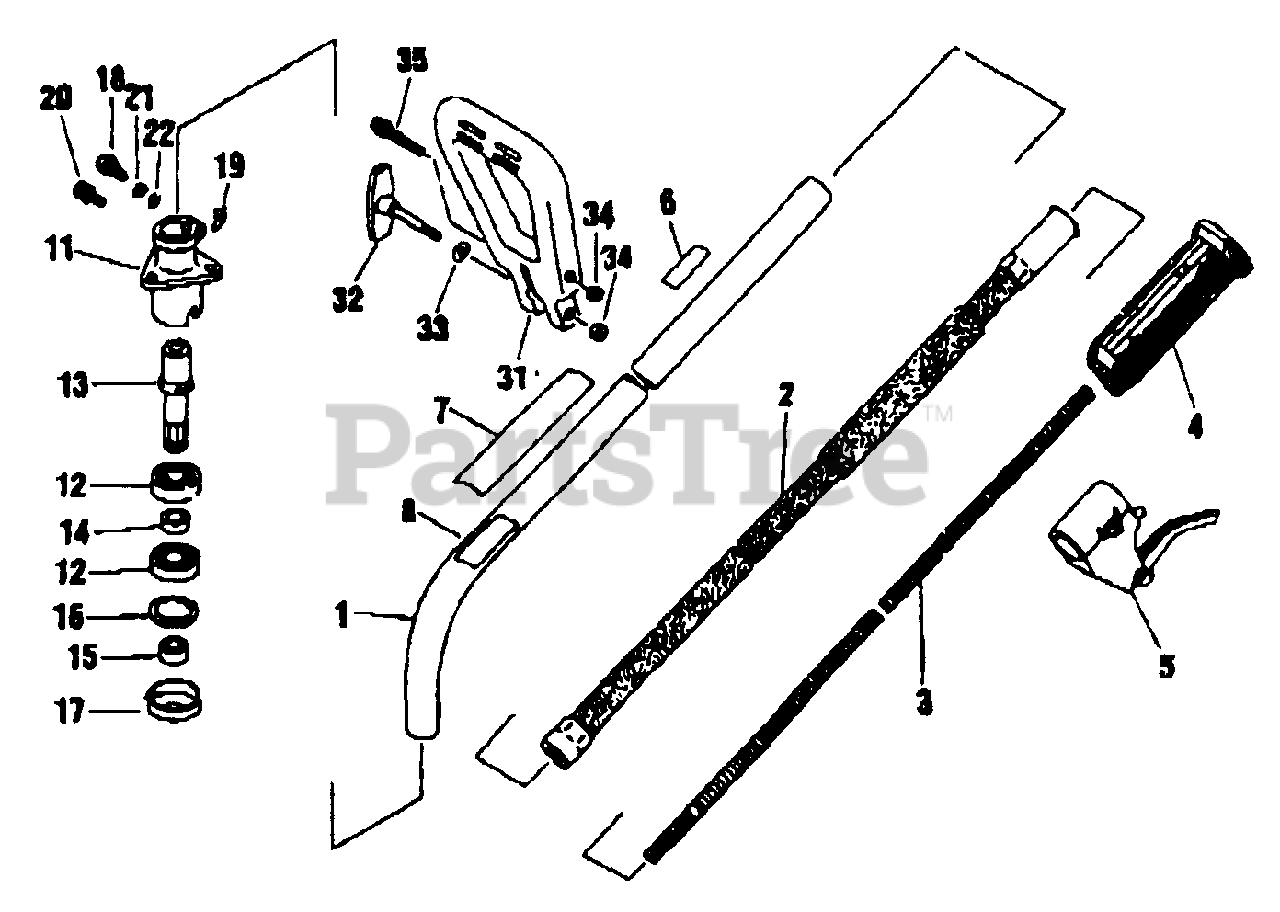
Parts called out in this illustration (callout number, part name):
1	PIPE, MAIN
2	LINER - FLEXIBLE
3	DRIVESHAFT - FLEXIBLE
4	GRIP
5	TRIGGER, THROTTLE
6	LABEL - ALIGNMENT
7	LABEL - MODEL
8	LABEL - CAUTION
11	CASE, GEAR
12	BEARING, BALL - 6001DDU
13	SHAFT
14	SPACER - UPPER
15	SPACER - LOWER
16	RING, RETAINING - 28
17	HOLDER
18	SCREW - 5X25
19	SHIM
20	SCREW - 5X10
21	LOCKWASHER - 5
22	WASHER - 5
31	HANDLE
32	THUMBSCREW
33	WASHER
34	NUT - 6
35	SCREW
